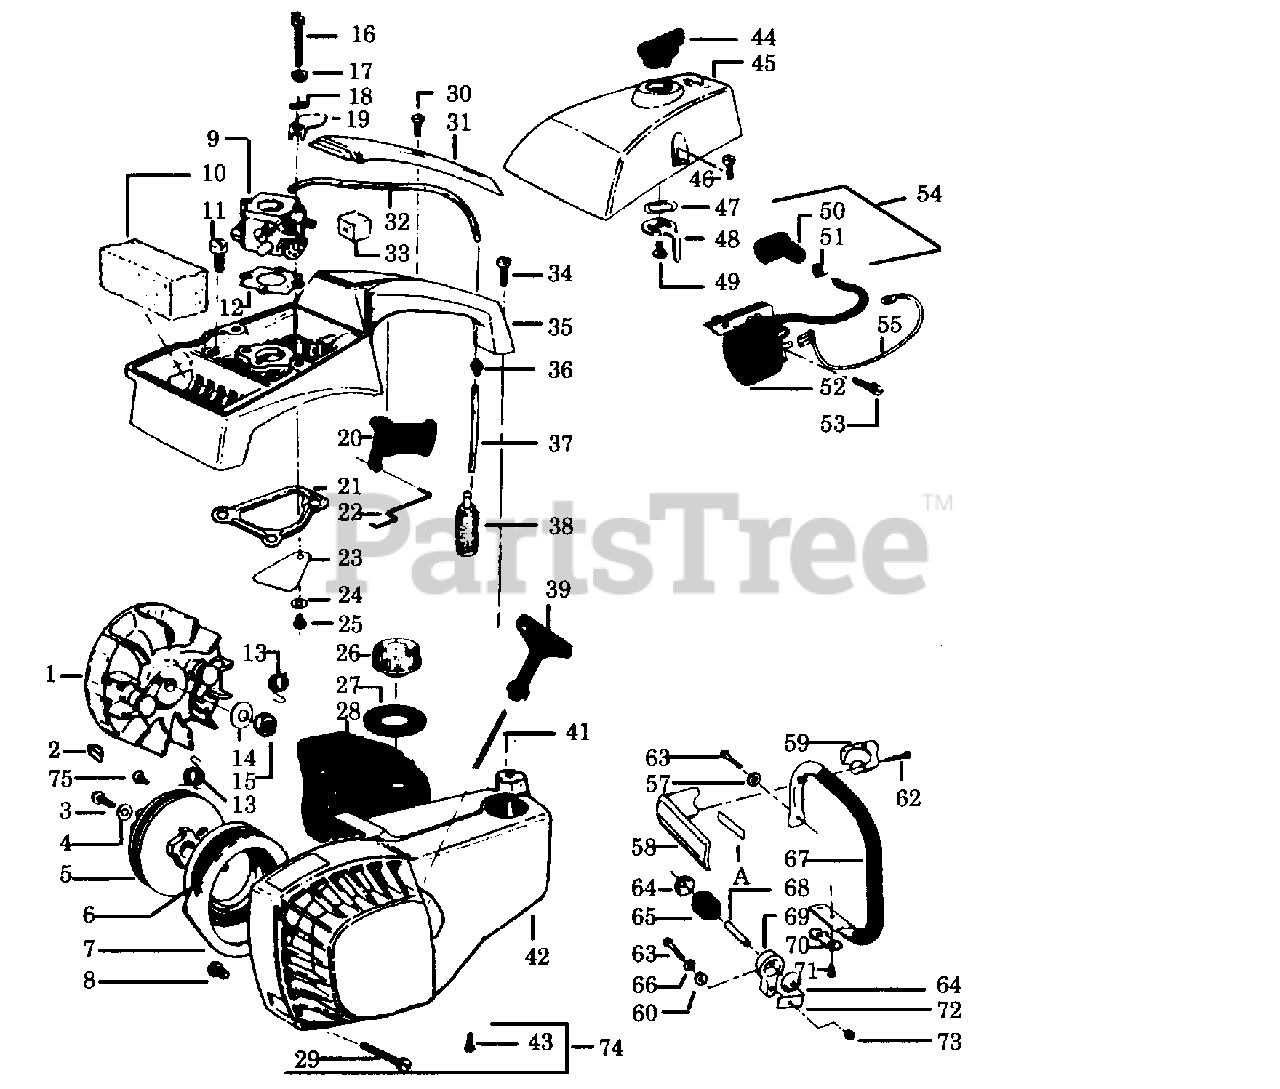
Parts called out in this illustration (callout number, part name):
1	FlywheelAss'y (Inc. #13)
2	Flywheel Key
3	Pulley Retaining Screw
5	StarterPulley
6	Starter Spring
7	Air Intake Baffle
9	Carburetor
10	Air Filter
13	Starter Dog Spring
18	Wave Washer
19	Choke Shutter
20	Throttle Trigger
21	Carb. Hsg. Gasket
22	Throttle Wire
23	Reed Valve
26	Fuel Cap Ass'y
28	Fuel Tank Ass'y.
31	Handle Cover
32	Fuel Line
33	Throttle Wire Boot
35	Handle & Carb. Hsg.
36	Fuel Line Fitting
37	Line Kit (Bulk 8133)
38	Fuel Pick-Up Ass'y.
39	Starter Handle
41	Rope Kit
42	Fan Hsg.-See Service Ref. 5
44	Choke Knob
45	Carb. Cover
48	Choke Lever
50	Spark Plug Boot
51	Spark Plug Connector
52	Ignition Module (Incl. #54&55)
54	Spark Plug Lead (Incl. #50&51)
55	Switch- Lead -See Service Ref. 2.
58	Handguard
59	Handguard Cap
64	Isolator Cup-See Service Ref. 1
65	Isolator
66	Lockwasher
67	Handlebar
69	Bracket Isolator
70	Retainer
72	Cork Pad
74	Fan Hsg. Screws Inc. 29,43, #9 of Power Unit
A	Handguard Decal
